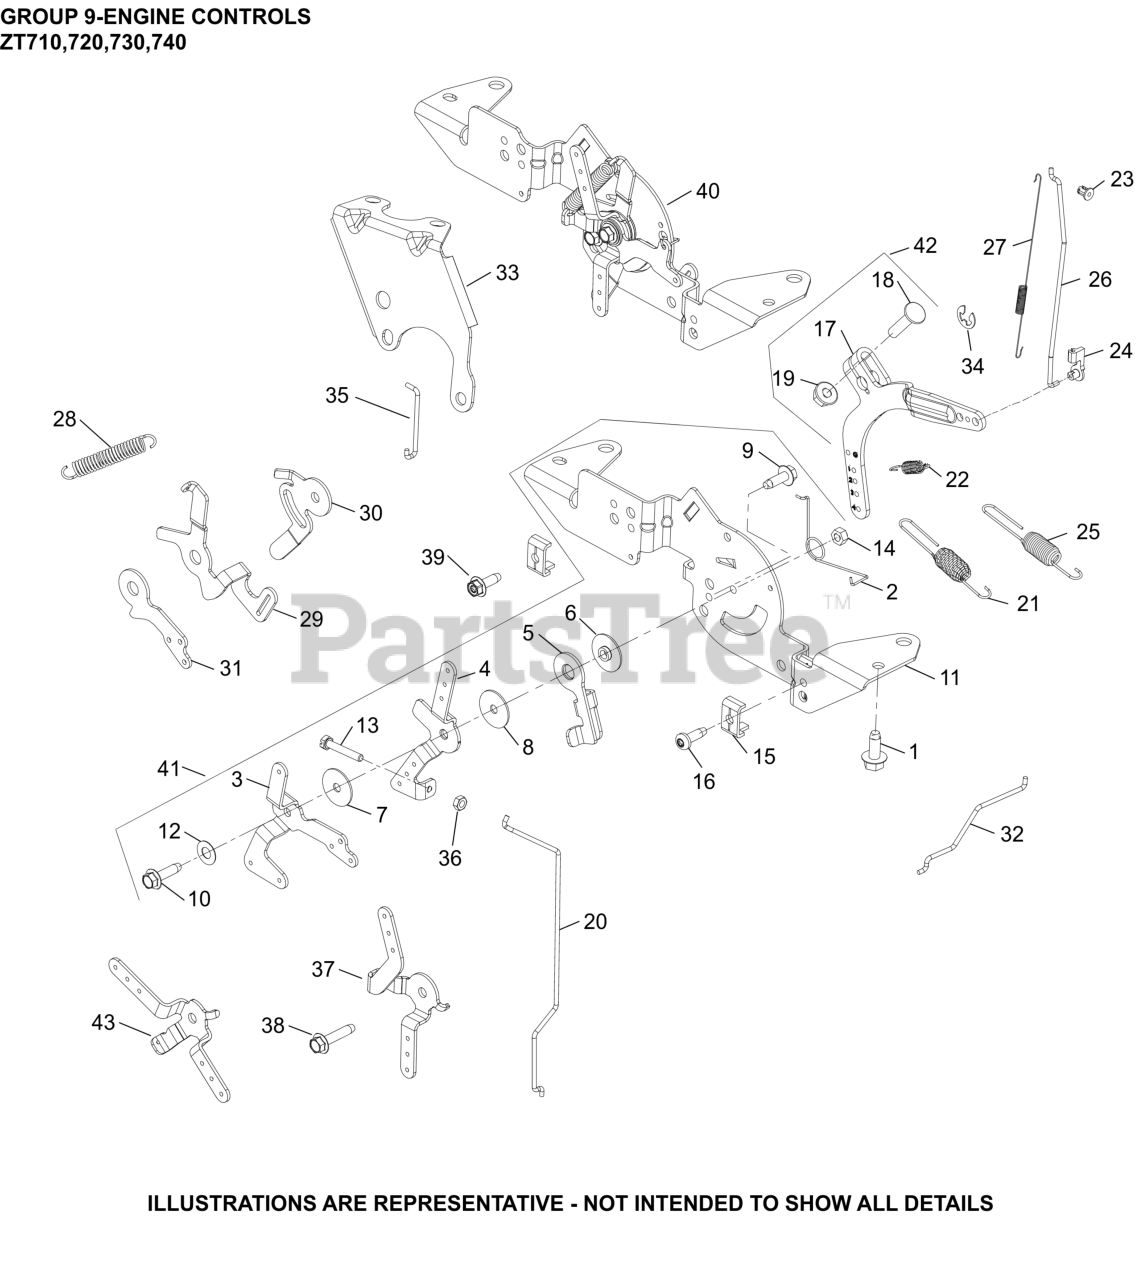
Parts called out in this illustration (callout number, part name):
1	SCREW, THREAD FORMING
2	SPRING, CHOKE RETURN
6	SPACER, CONTROL ASSEMBLY
7	WASHER, FLAT 5.5 MM
9	SCREW, THREAD FORMING
11	BRACKET, SPEED CONTROL
12	WASHER, SPRING 1/4"
14	NUT, LOCK M5X.8
15	CLAMP, CABLE CABLE
17	LEVER, GOVERNOR - (#2409069S)
18	BOLT, RD HD SQ NECK M6X1.0X25
19	NUT, FLG M6X1.0
22	SPRING, GOVERNED IDLE
23	BUSHING, LINKAGE RETAINING
24	BUSHING, THROTTLE LINKAGE
25	SPRING, GOVERNOR (PURPLE)
27	SPRING, LINKAGE
28	SPRING, SPEED CONTROL
29	LEVER, GOVERNOR SPRING
30	LEVER, SPEED SETTING
32	LINKAGE, THROTTLE
34	CLIP, RETAINER GOVERNOR SHAFT
38	SCREW, THREAD FORMING-USE 25 086 472-S
39	SCREW, THREAD FORMING
40	SPEED CONTROL, ASSY SINGLE WIRE
42	LEVER, GOVERNOR ASSEMBLY
43	LEVER, SPEED CONTROL
